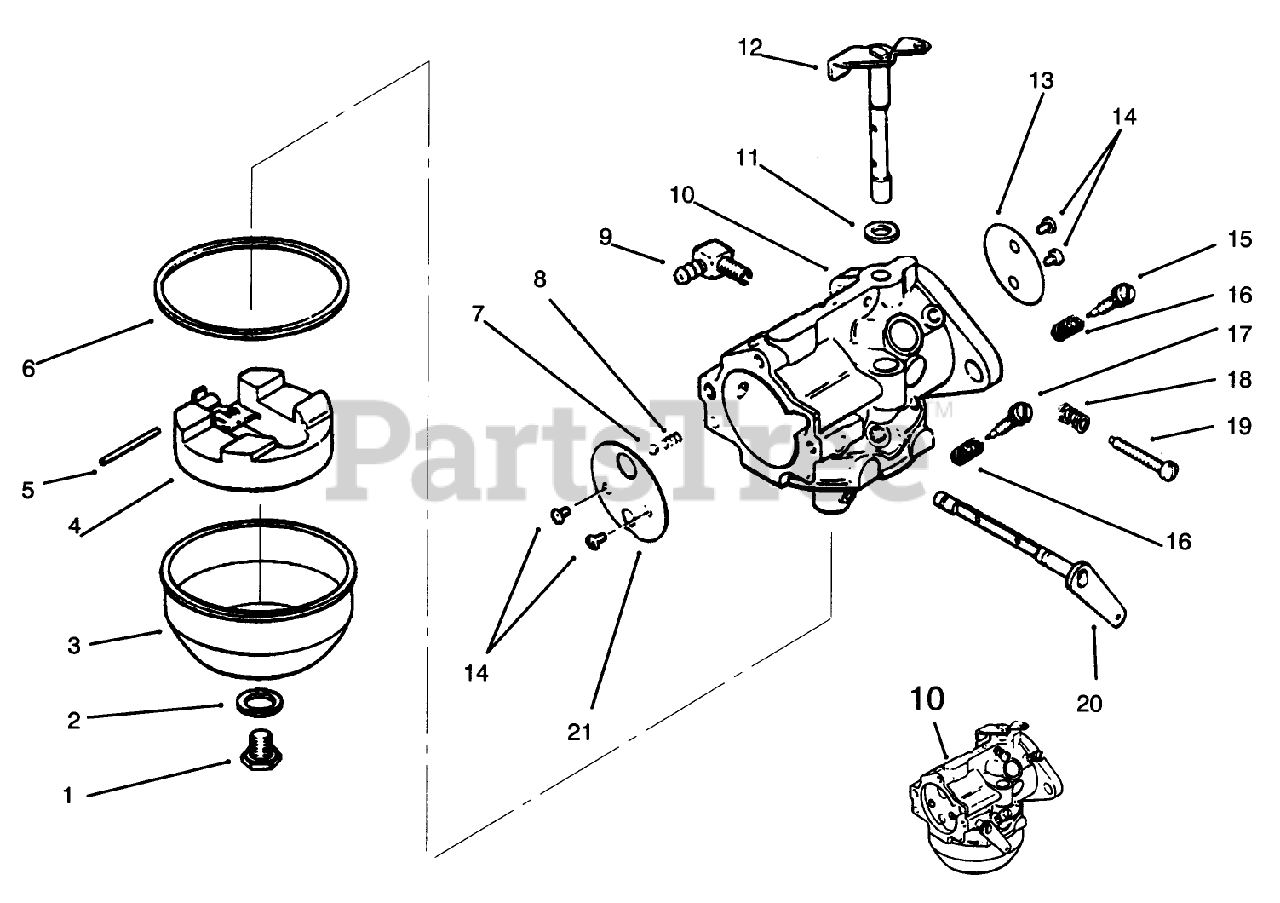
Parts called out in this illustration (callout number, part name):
1	KOHLER 25-100-05
2	KOHLER 25-041-03
3	KOHLER 25-104-01
4	KOHLER 25-757-09
5	Pin-Float
6	KOHLER 25-041-04
7	KOHLER 25-194-01
8	KOHLER 25-089-03
9	Connector 90 Deg.
10	KOHLER 47-853-20
11	Seal ASM
12	KOHLER 457-144-21
13	KOHLER 25-146-02
14	KOHLER 25-086-27
15	KOHLER 25-368-01
16	KOHLER 25-089-02
17	Main-Needle
18	KOHLER 25-089-04
19	KOHLER 25-086-26
20	KOHLER 47-090-38
21	KOHLER 47-146-08
